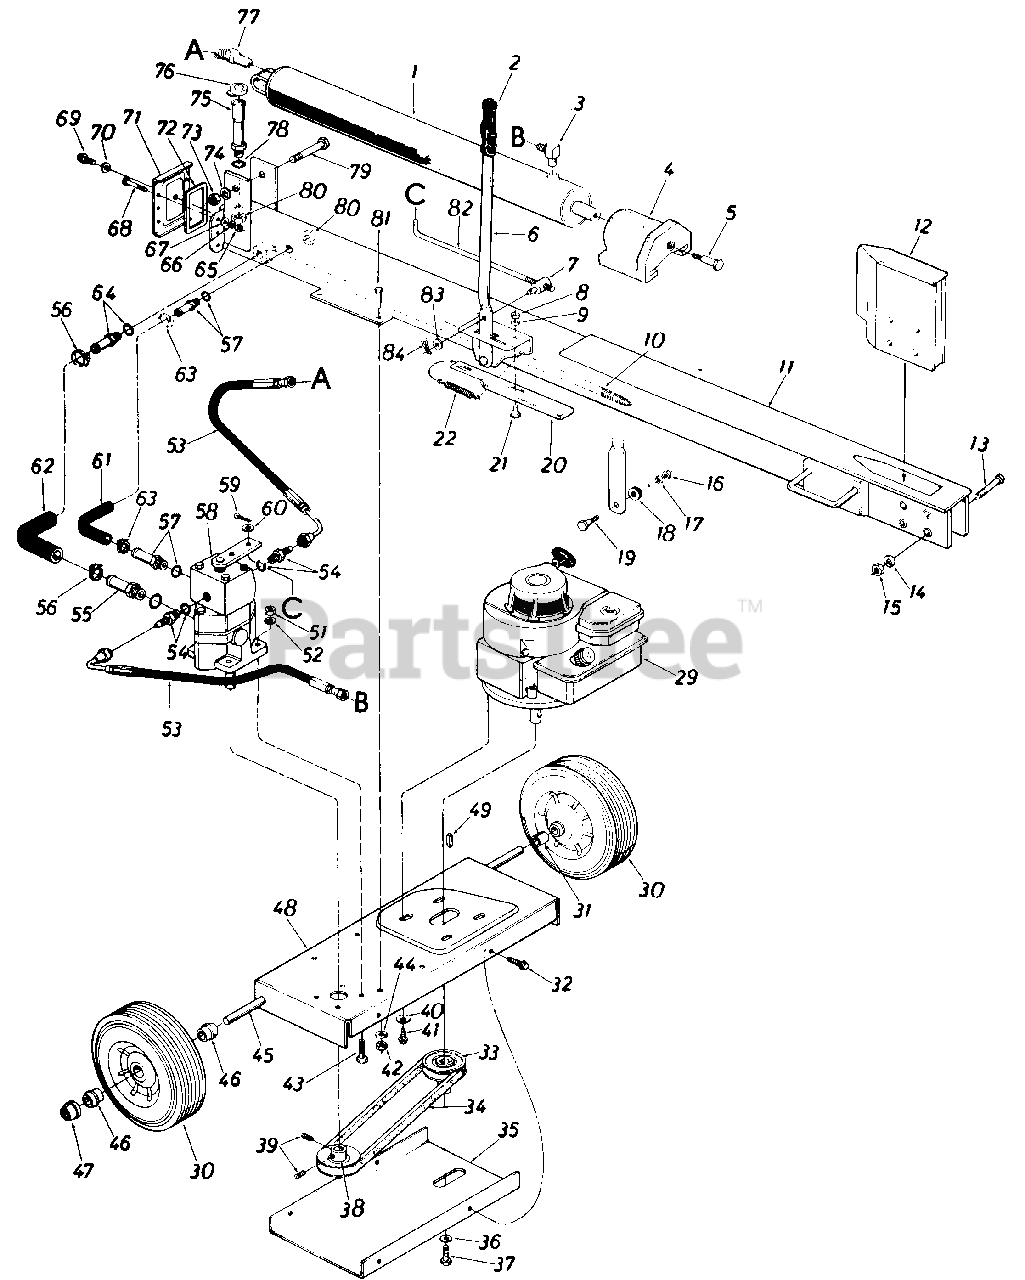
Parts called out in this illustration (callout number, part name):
1	CYLINDER-HYDRO
2	GRIP-LIFT HANDLE
3	ADAPTER-90 DEGREE
4	PLATE-PUSH
5	SCREW-SHLD .62X.475
7	FERRULE-ADJ
8	NUT-HEX 5/16-18
9	WASHER-LOCK-5/16
10	TUBE ASSY-STRAINER
11	TANK ASSY-OIL
12	WEDGE ASSY
13	SCREW-HEX 5/8-18 X 3.50
14	WASHER-LOCK-5/8
15	NUT-HEX 5/8-18
16	NUT-HEX 3/8-16
17	WASHER-LOCK-3/8
18	WASHER-RUBBER .50 X 1.00 X .25
19	SCREW-SHLD .498 DIA X .340
20	BRACKET-ENGAGE
21	SCREW-SHLD .437 DIA X .180
22	SPRING-EXTENSION
30	WHEEL ASSY W/TIRE-10 X 2.75
31	SLEEVE
32	SCREW-HEX WASH SF TAPP
34	BELT-V 1/2 X 30
35	COVER-BELT
36	WASHER-LOCK-5/16
37	BOLT-3/8 NF X 1"GR5
39	SCREW-SET 1/4-28 X .25
40	WASHER-BELL .400 ID X .88 X .060
41	SCREW-HEX WASH HD 3/8-24 X 7/8
42	NUT-5/16-24
43	SCREW-HEX 5/16-18 X 1.00
44	WASHER-LOCK-5/16
45	SHAFT-AXLE
46	BEARING-FLANGE
48	FRAME-ENGINE
49	KEY-SQ 3/16X1.50
51	NUT-HEX 5/16-18
52	WASHER-LOCK-5/16
53	HOSE-PRESSURE
56	CLAMP-HOSE-5/8
58	PUMP ASSY
59	PIN-COTTER-3/32 DIA X .75
60	WASHER-FL-.344 X .62
61	HOSE-RETURN-90 DEG
62	HOSE-SUCTION-90 DEG
63	CLAMP-HOSE 1/4 ID
65	NUT-HEX 5/16-18
66	WASHER-LOCK-5/16
67	WASHER-FL (#46041)
68	SCREW-HEX 5/16-18 X 1.50
69	SCREW-HEX WASH HD 5/16-18
70	WASHER-GASKET
71	PLATE-END
73	NUT-HEX 3/4
74	WASHER
75	TUBE ASSY-FILLER
76	CAP ASSY-GAS
77	ADAPTER-45 DEGREE
79	SCREW-HEX 3/4X4.0
80	NUT-HEX 1 1/16-12
81	SCREW-HEX SPECIAL 5/16-24X1.0
82	ROD-ENGAGEMENT
83	WASHER-FL-.344 X .62
84	PIN-INTERN COT-5/16 DIA
